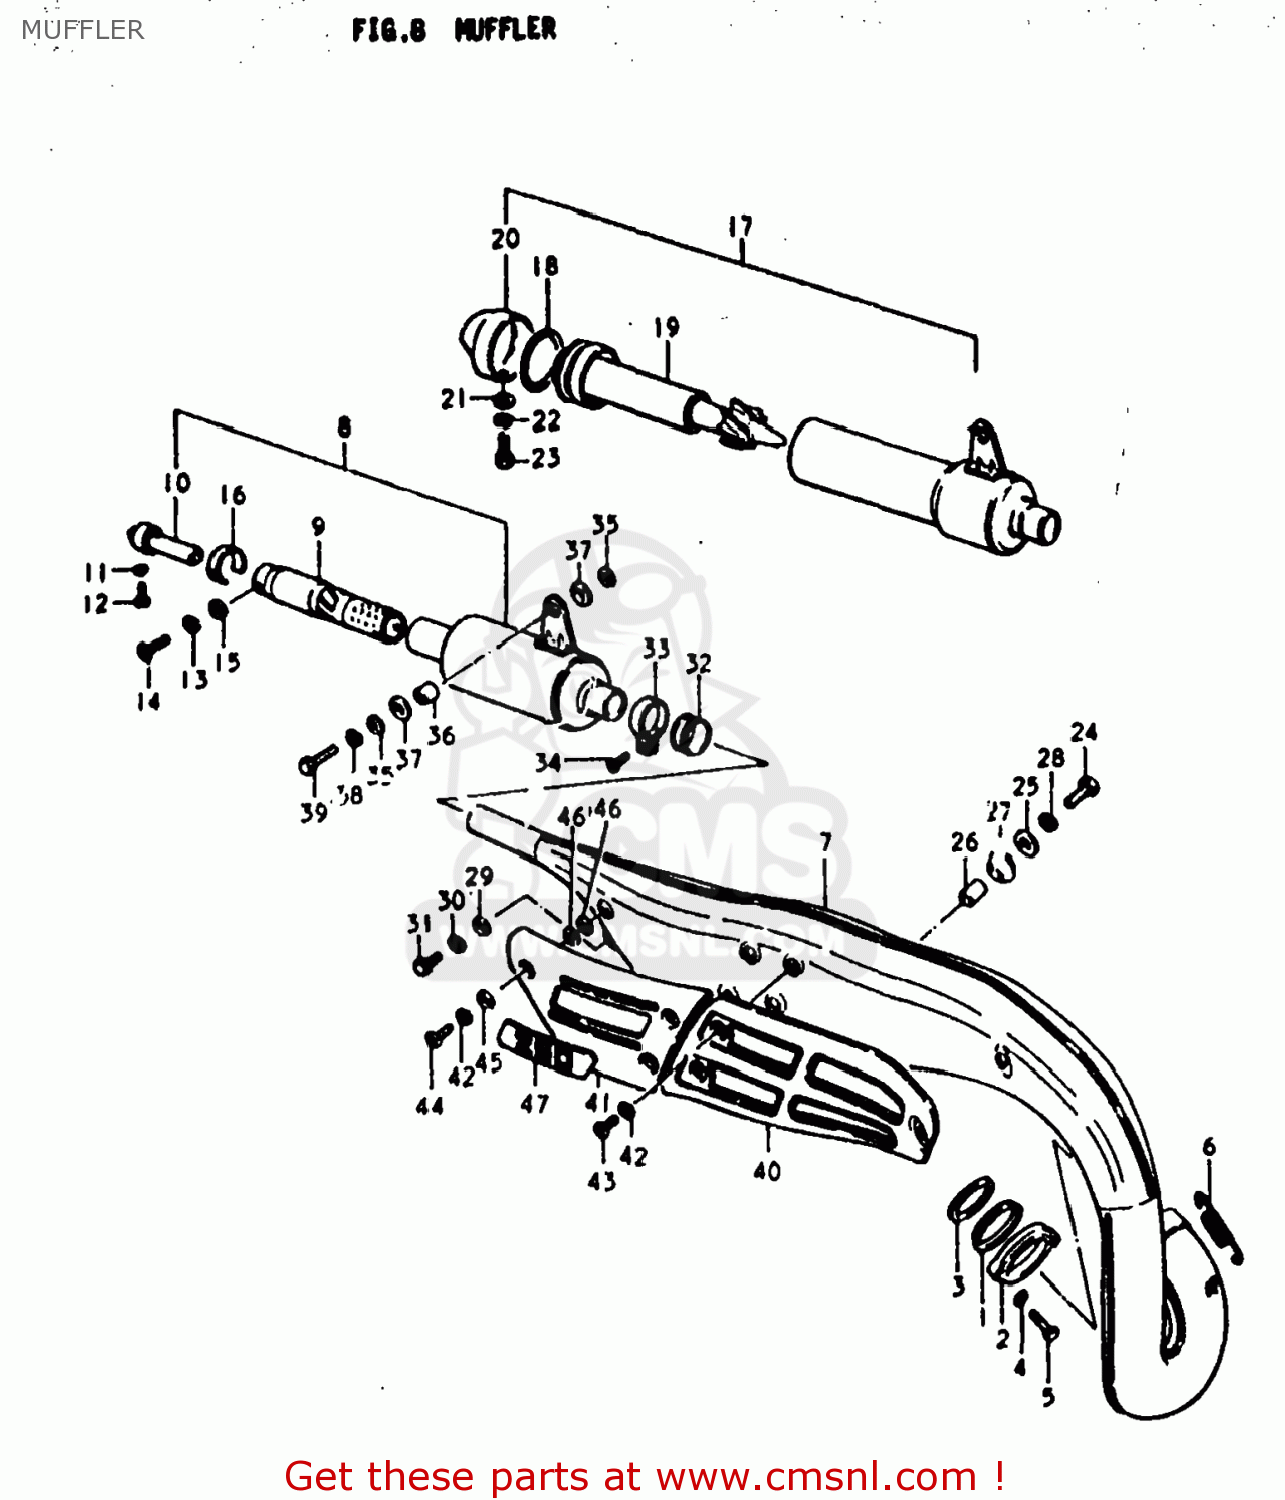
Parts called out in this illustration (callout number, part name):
1	GASKET,EXHAUST PIPE (NAS)
2	CLAMP,EXHAUST PIPE
3	GASKET,EXHAUST PIPE
4	LOCK WASHER
5	BOLT
6	SPRING
7	BODY,MUFFLER
8	MUFFLER ASSEMBLY
9	ARRESTER,SPARK
10	TUBE,MUFFLER CLEAN OUT
11	LOCK WASHER
12	SCREW
13	LOCK WASHER
14	SCREW(6X8)
15	WASHER
16	BAND,SPARK ARRESTER
17	MUFFLER ASSEMBLY
18	O-RING (D:3.5 ID:54.4)
19	TUBE,MUFFLER CLEAN OUT
20	COVER,SECOND MUFFLER TAIL
21	WASHER
22	LOCK WASHER
23	SCREW(6X8)
24	BOLT (8X30)
25	WASHER (8.7X22X2)
26	SPACER (8X12X15)
27	DAMPER,MUFFLER,FR
28	LOCK WASHER
29	WASHER
30	LOCK WASHER
31	BOLT
32	CONNECTOR,MUFFLER
33	CLAMP
34	SCREW
35	WASHER
36	SPACER (8.6X13.8X9)
37	CUSHION
38	LOCK WASHER
39	BOLT
40	COVER,MUFFLER
41	COVER,MUFFLER
42	LOCK WASHER
43	SCREW
44	SCREW 6X12
45	WASHER
46	GASKET 6.2X12X1.5 (MCA)
47	EMBLEM,MUFFLER COVER
